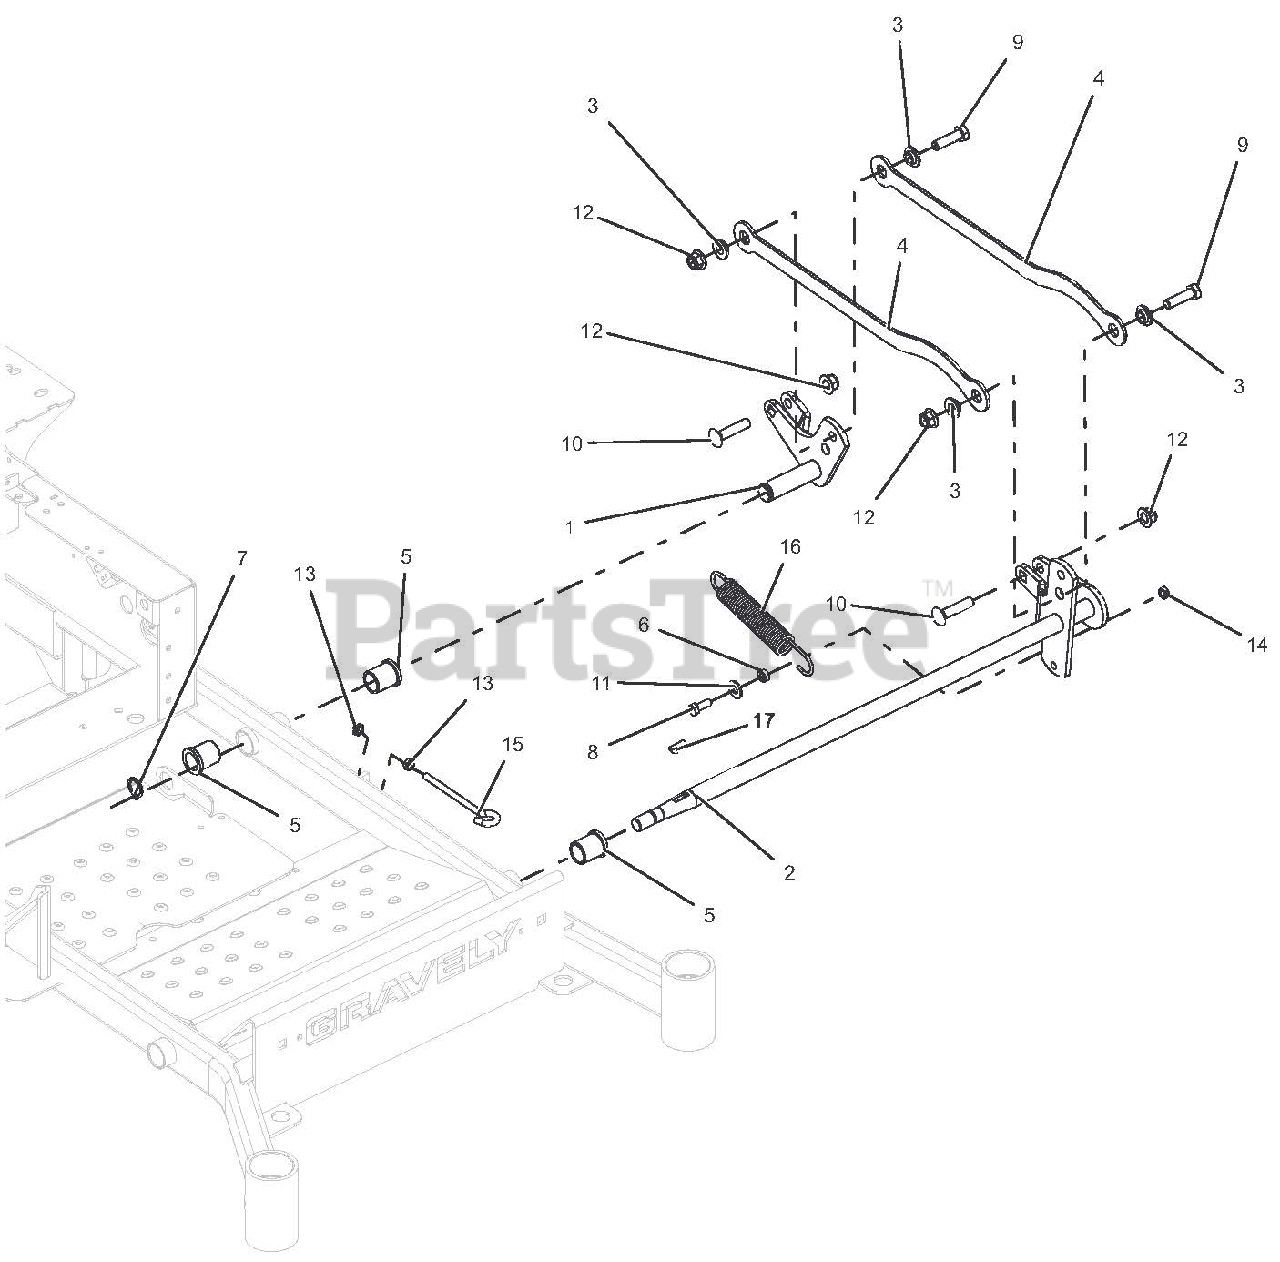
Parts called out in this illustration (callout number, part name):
1	WLDMT, LH REAR DECK LIFT
2	WLDMT, PT100 FRONT LH DECK LIFT-BLACK
3	BSHG, FLANGE .515X.750X.31X1.12
4	LINK, LIFT - BLK
5	BSHG-FLG 1.00X1.25X1.5X1.5
6	BSHG, SLV .377X.624X.235
7	RG-RTNG-EXT 1.00X.078
8	BLT-HEX .38-16X1.00 GR5 YWZC
9	BLT-HEX .50-13X1.75 GR5 YWZC
10	BLT-RDHDSQNK .50-13X2.25 G5 Y
11	WSHR-FL-STL.438X1.00X.083 YWZC
12	NUT-LK-NYL-FLG .50-13 YWZC
13	NUT, JAM .375-16 YWZC
14	@NUT-LK-CTR-JAM .375-16 YWZC
15	BOLT, EYE .38-16X6.00 .62 DIA
16	SPRG, TENSION .162 X 1.250 X 8.250
17	KEY, WDRF .25 X 1.00 HRD #15
